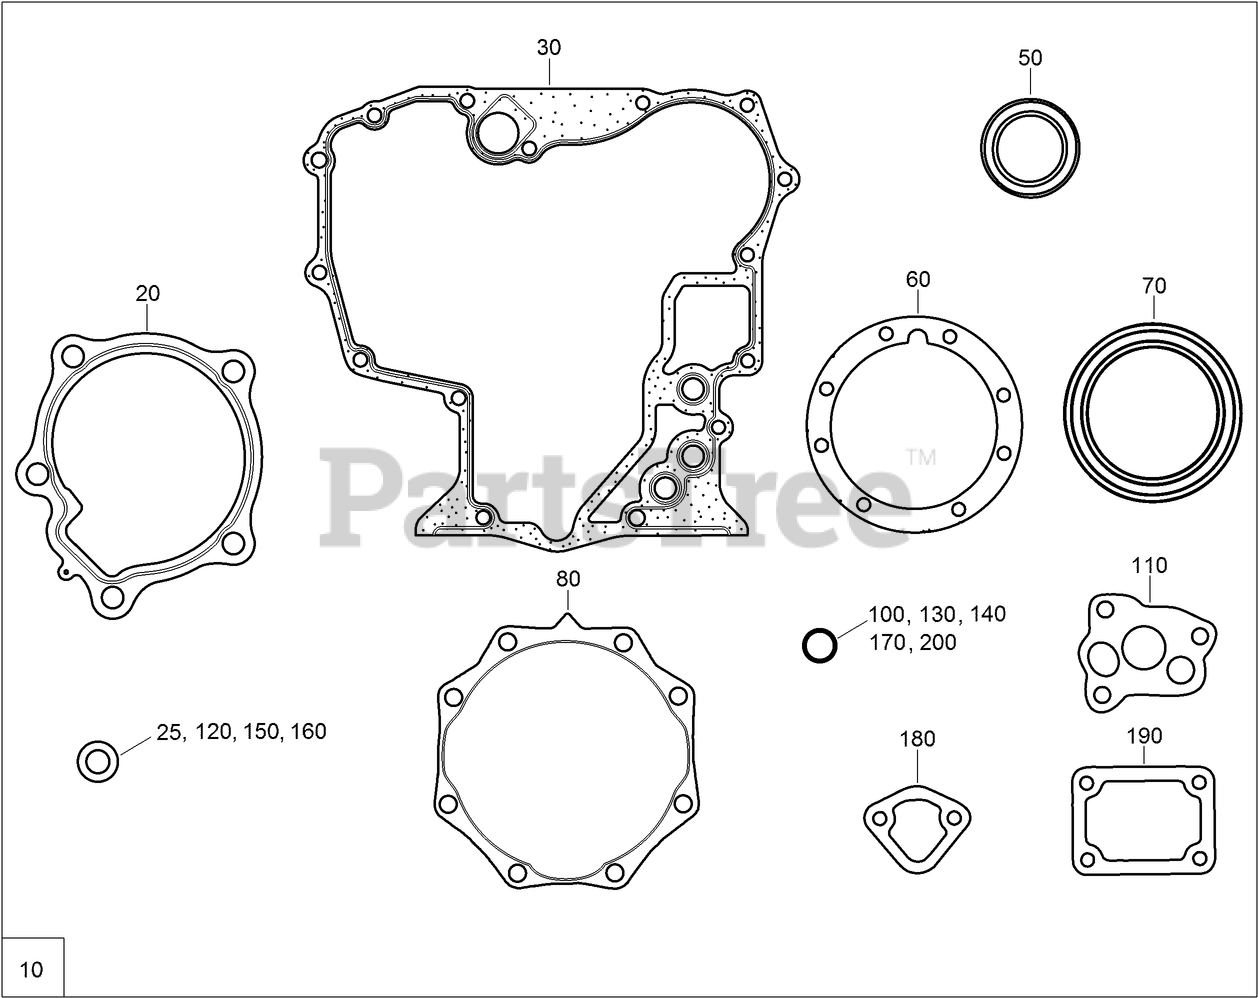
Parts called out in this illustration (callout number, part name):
10	LOWER GASKET KIT
20	GASKET-PUMP, WATER
25	GASKET
30	GASKET-CASE, GEAR
50	SEAL-OIL
70	SEAL-OIL
80	GASKET-COVER, CASE
100	O-RING
110	GASKET-PUMP, OIL
120	GASKET
130	O-RING
140	O-RING
150	GASKET
160	GASKET-PAN, OIL
170	O-RING
180	GASKET-PUMP, FUEL
190	GASKET-PLATE, CONTROL
200	O-RING
